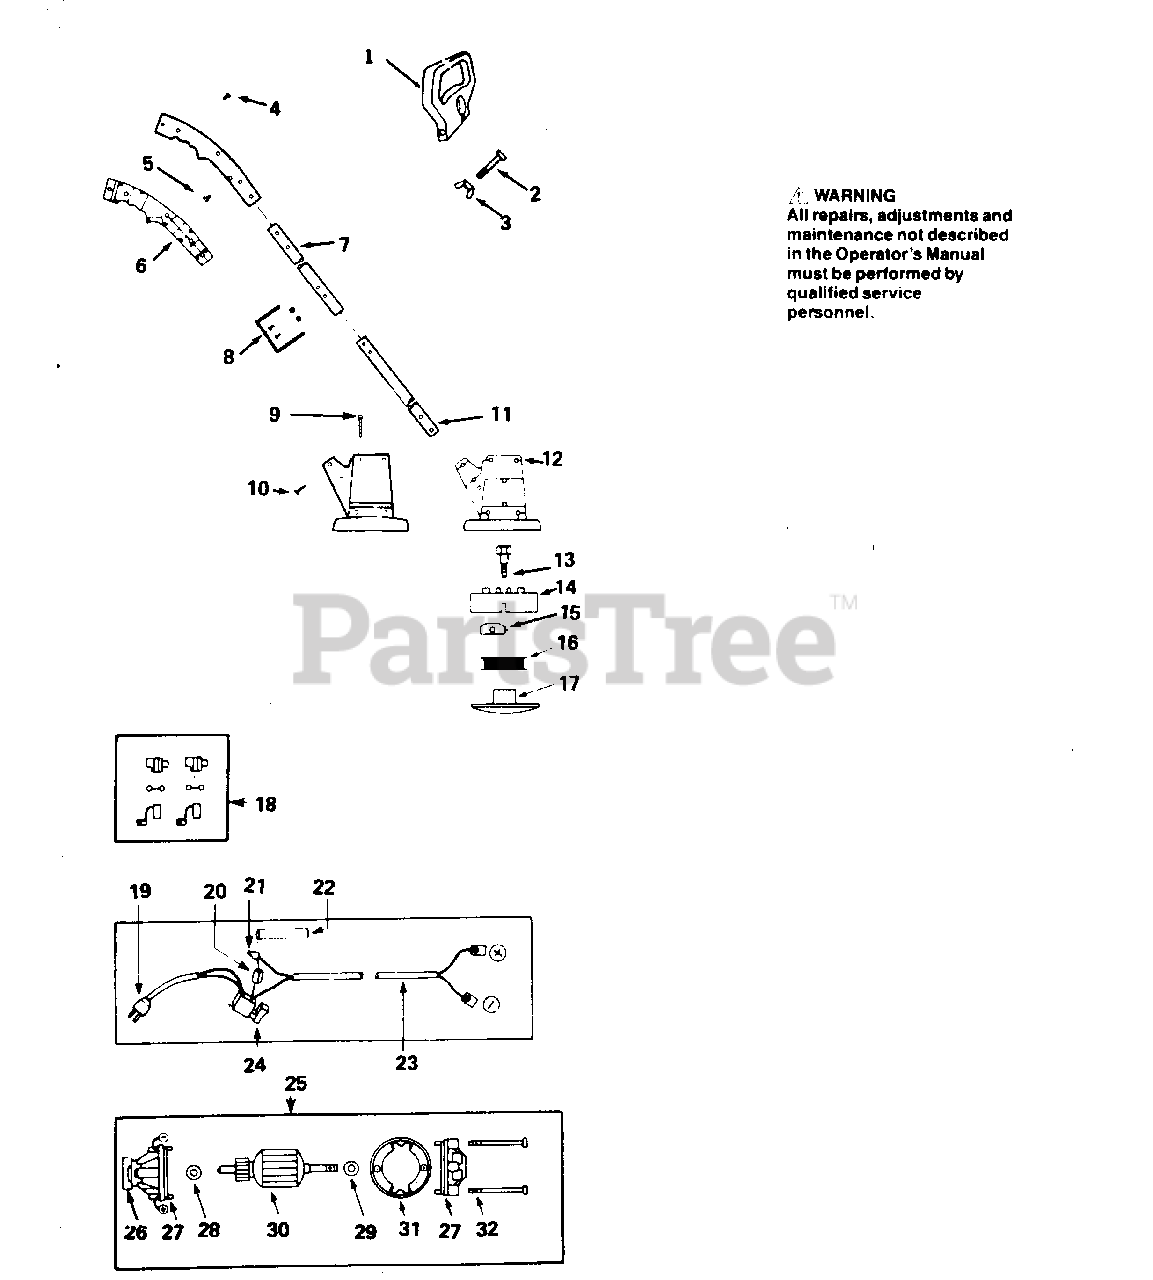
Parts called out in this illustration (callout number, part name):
1	ASSIST HANDLE
3	WING NUT
6	TRIGGER HANDLE SET
7	TUBE, UPPER
8	TUBE FASTENER KIT
11	TUBE, LOWER
12	MOTOR HOUSING SET
13	DRIVE ADAPTOR
15	LINE SAVER
16	SPOOL. WOUND
17	BALL LOCK
18	BRUSH KIT
19	POWER CORD
21	CONNECTOR
26	INSULATOR
27	END BELL SET
28	WASHER - THRUST, .025"
29	WASHER - THRUST, .010"
30	ARMATURE
31	FIELD ASSEMBLY
